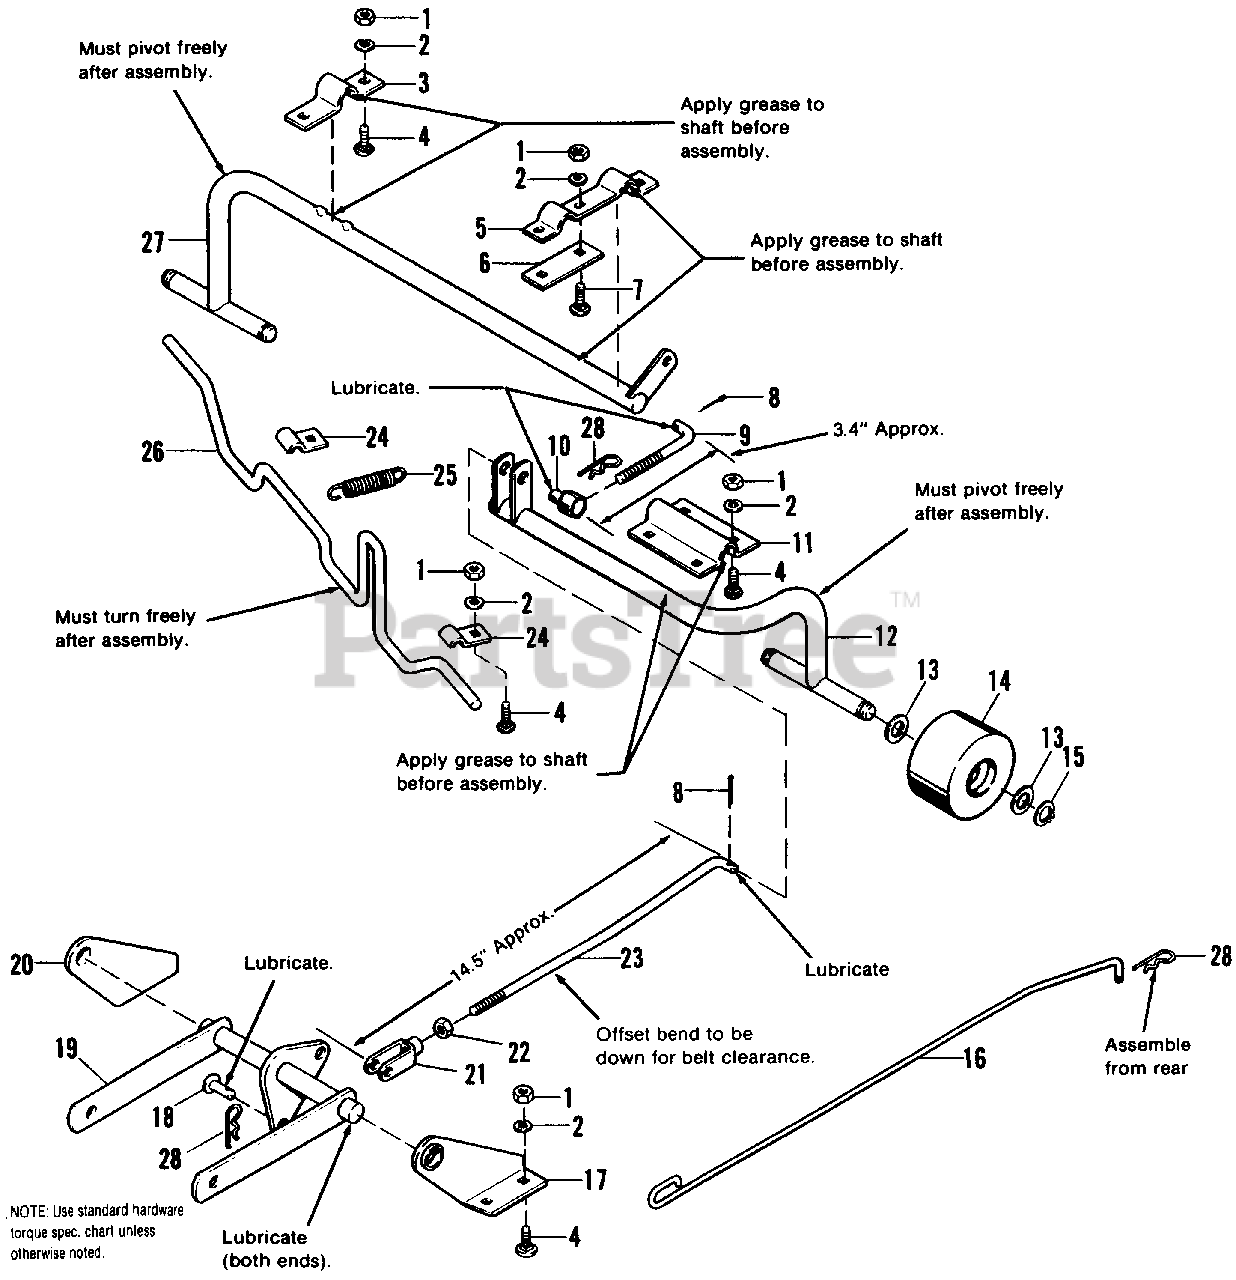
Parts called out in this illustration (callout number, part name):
1	NUT, Hex, 5/16-18
2	LOCKWASHER, 5/16
4	BOLT, Carriage, 5/16-18 x 3/4
5	CLAMP, Wheel Support
7	BOLT, Carriage, 5/16-18 x 1
8	PIN, Cotter, 3/32 x 3/4
12	WHEEL SUPPORT ASSY., L.H.
13	WASHER, 41/64
15	RING, Retainer
16	ROD, Brake
17	BRACKET, Front, L.H.
18	PIN, Yoke
19	SUPPORT ARM ASSY.
20	BRACKET, Front, R.H.
21	CLEVIS, Adjusting
22	NUT, Hex, 3/8-16
23	ROD, Link
25	SPRING
26	BRAKE, Mower
27	WHEEL SUPPORT ASSY., R.H.
28	CLIP, Hairpin
